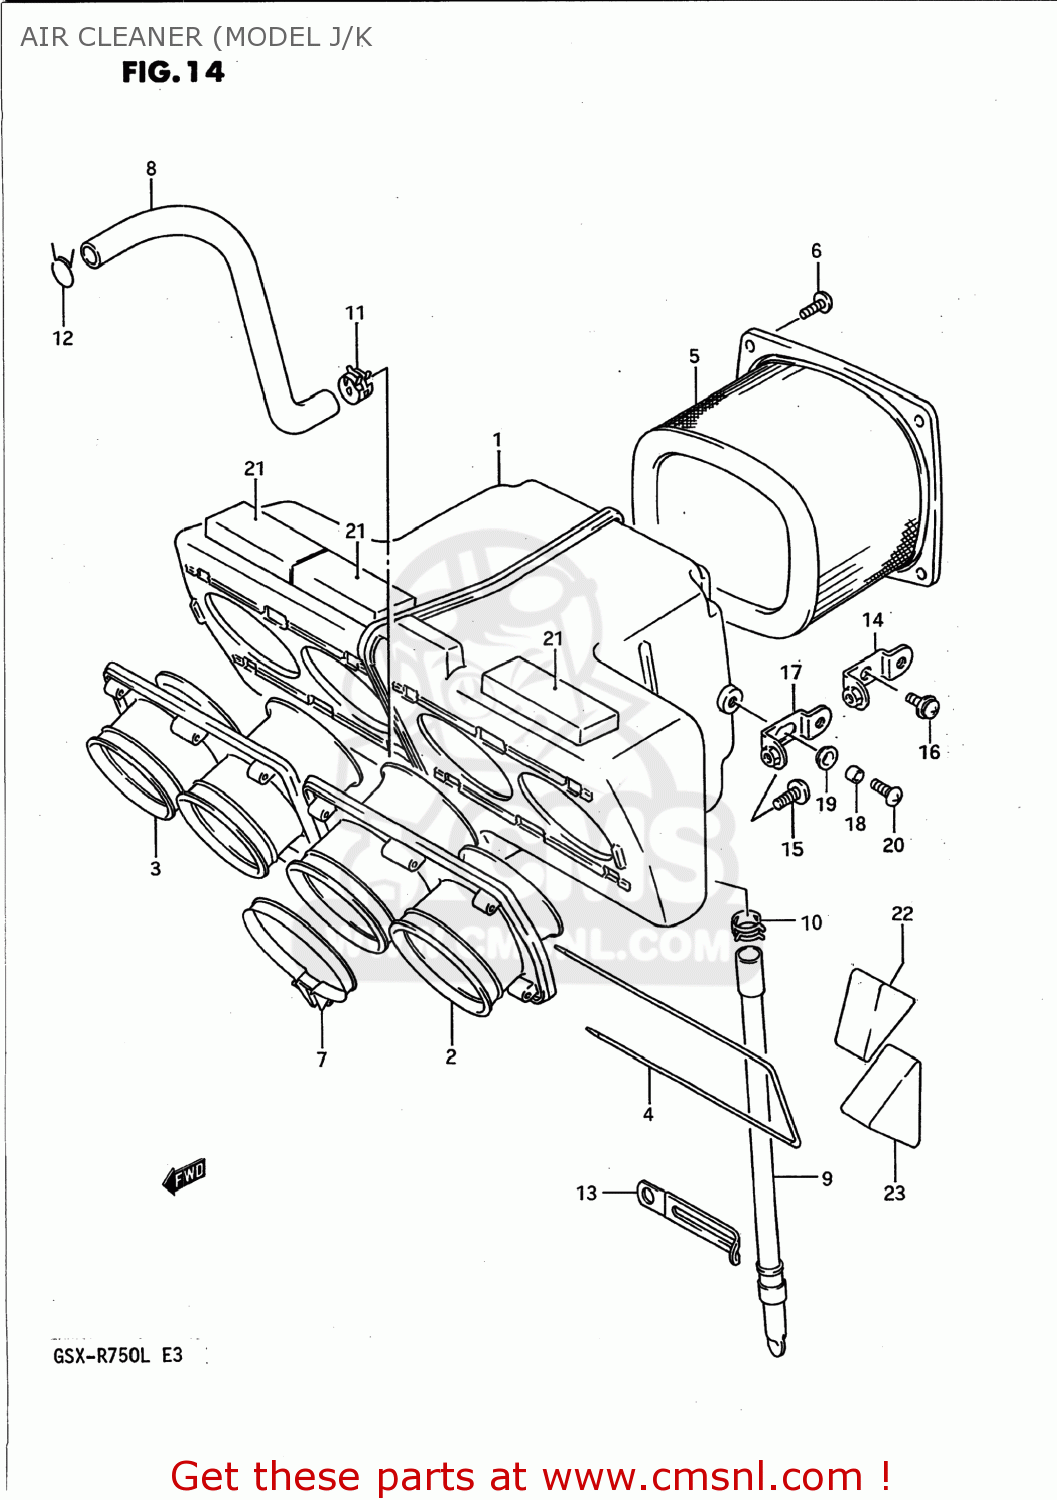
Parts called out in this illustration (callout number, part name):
1	CASE,AIR CLEANER
2	TUBE,AIR CLEANER OUTLET LH
3	TUBE,OUTLET,R
4	SHAFT,OUTLET TUBE
5	FILTER ASSY,AIR CLEANER
6	SCREW
7	CLAMP
8	TUBE,BREATHER
9	DRAIN TUBE
10	CLIP
11	CLIP
12	CLIP
13	CLAMP
14	BRACKET COMP,AIR CLEANER
15	SCREW
16	SCREW
17	BRACKET,AIR CLEANER CASE
18	SPACER
19	WASHER
20	SCREW
21	CUSHION,AIR CLEANER CASE
22	CUSHION,AIR VENT HOSE
23	CUSHION,AIR VENT HOSE
